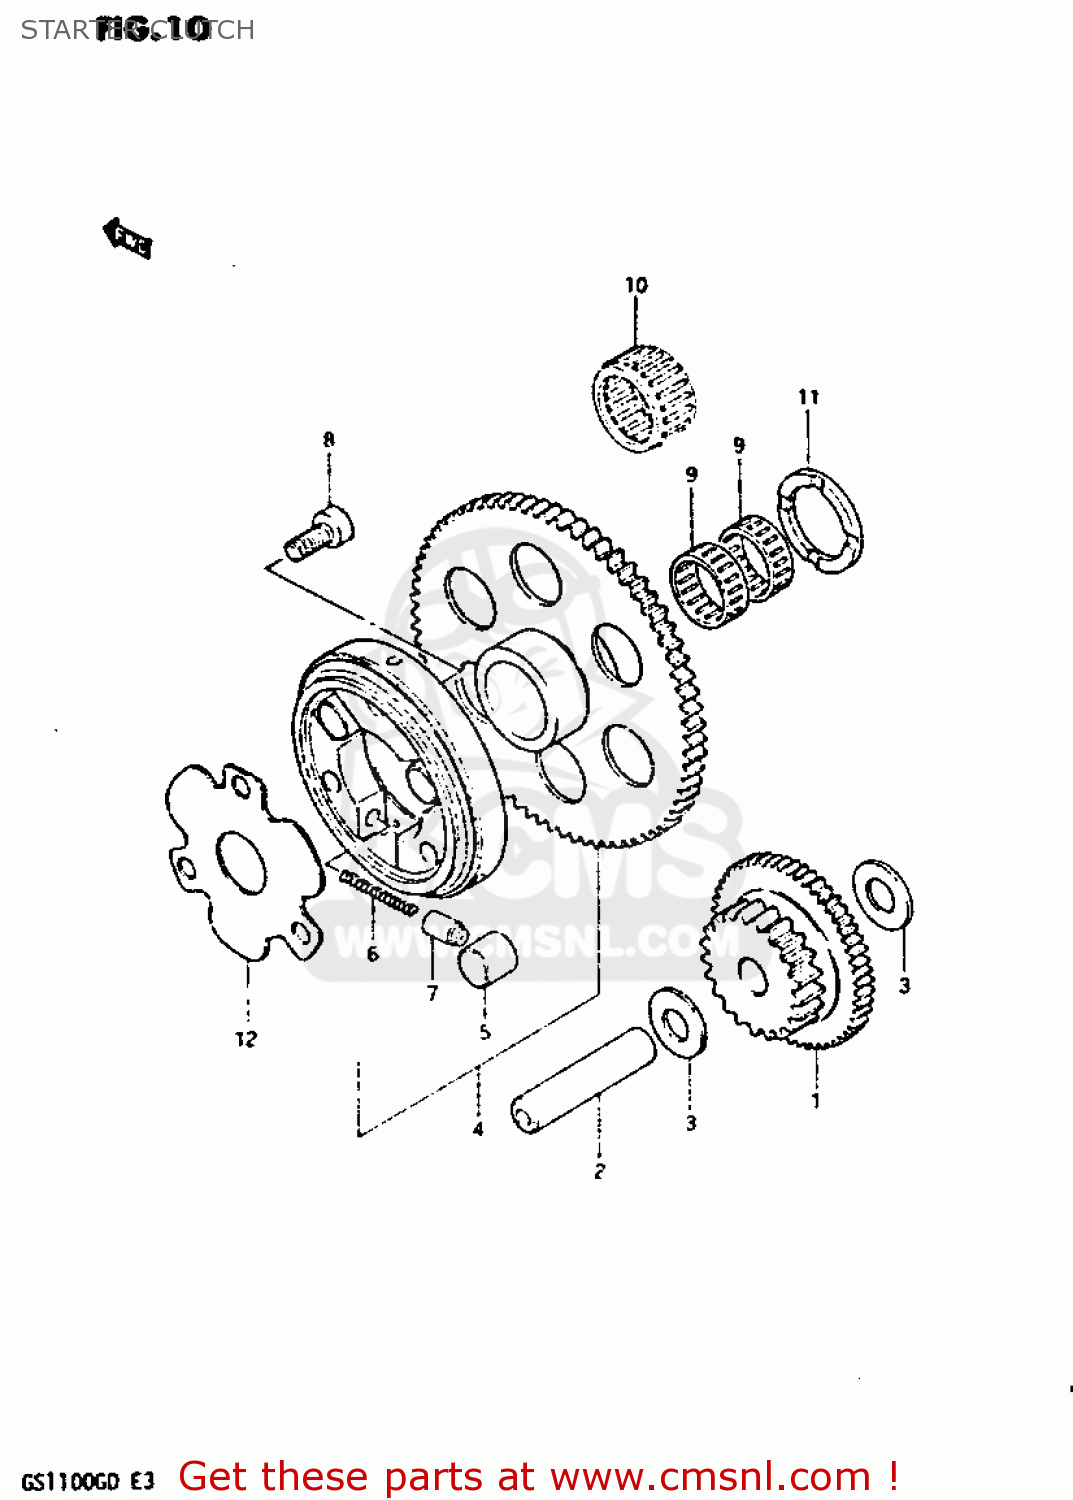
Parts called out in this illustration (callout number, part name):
1	GEAR,STARTER IDLE
2	PIN(7.4X13X56)
3	WASHER(13.3X25X0.85)
4	CLUTCH SET,STARTER
5	PIN(14X13)
6	SPRING
7	PIECE,PUSH
8	BOLT
9	ROLLER BEARING (25X31X2
10	ROLLER BEARING (25X31X2
11	WASHER(25X38X2.5)
12	SHIM,STARTER CLUTCH HUB
